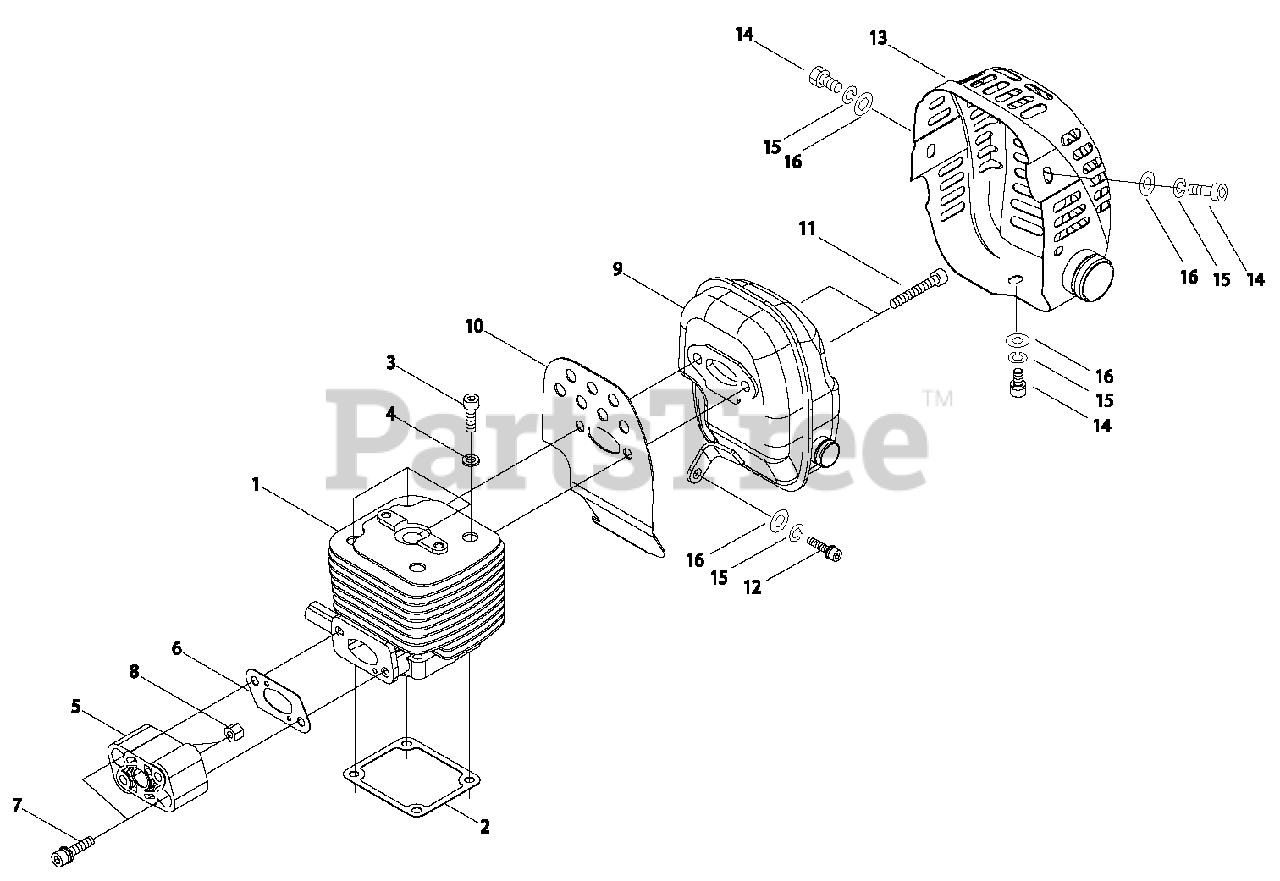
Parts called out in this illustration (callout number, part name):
1	CYLINDER
2	GASKET, CYLINDER
3	BOLT 5×25
4	WASHER, SPRING 5
5	INSULATOR
6	GASKET, INTAKE
7	BOLT M5×25
8	NUT
9	MUFFLER
10	HEAT SHIELD, EXHAUST
11	BOLT 6
12	BOLT 5
13	COVER, MUFFLER
14	BOLT 5×10
15	WASHER, SPRING 5
16	WASHER 5.5×12×0.8
